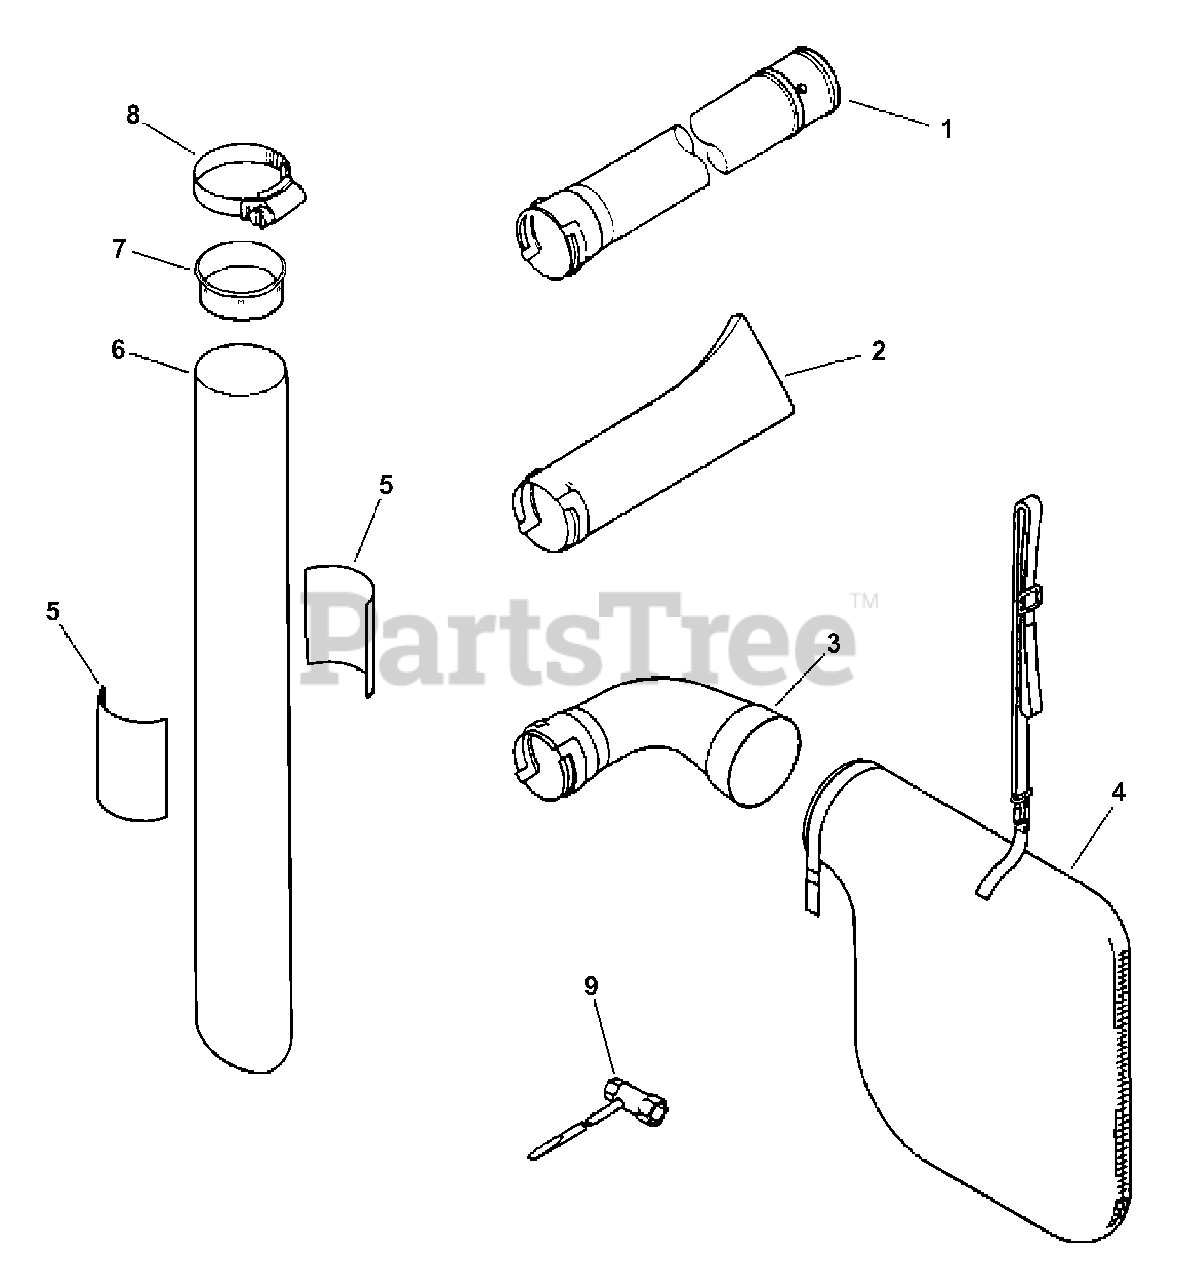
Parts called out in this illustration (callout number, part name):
1	TUBE, BLOWER - STRAIGHT
2	TUBE, BLOWER - NOZZLE
3	TUBE, DEBRIS
4	BAG, DEBRIS
5	LABEL - MODEL
6	TUBE, VACUUM
9	T-WRENCH - 13X19mm
